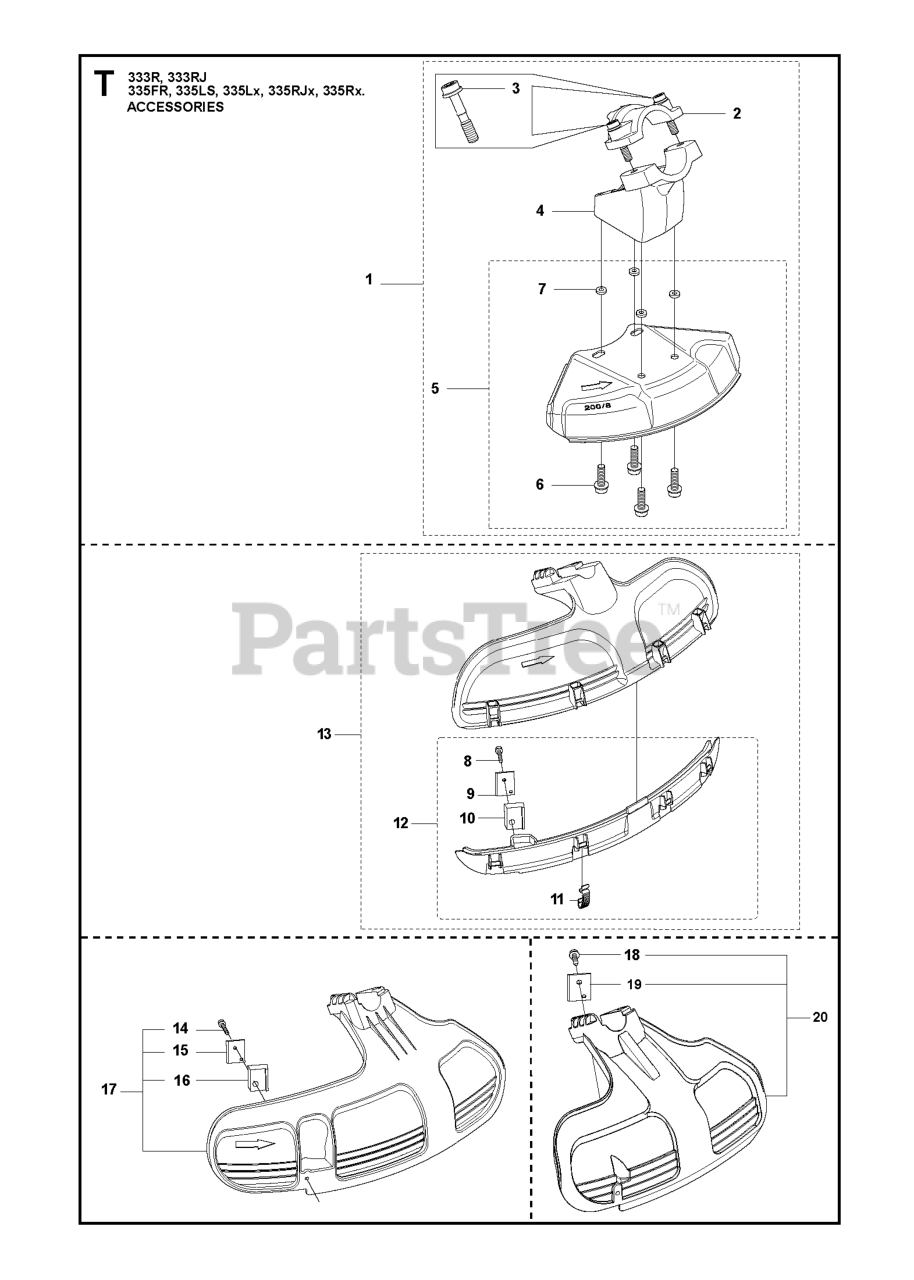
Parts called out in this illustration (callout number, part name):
1	ADAPTER
2	CLAMP
3	SCREW IHSCFMO
4	ADAPTER
5	BLADE GUARD
7	LOCKING NUT
8	SCREW
9	LINE CUTTER
10	DISTANSBLOCK
12	SPLASH GUARD
13	COMBI PROTECTOR
15	LINE CUTTER
16	DISTANSBLOCK
19	LINE CUTTER
20	TRIMMER GUARD ASSY
